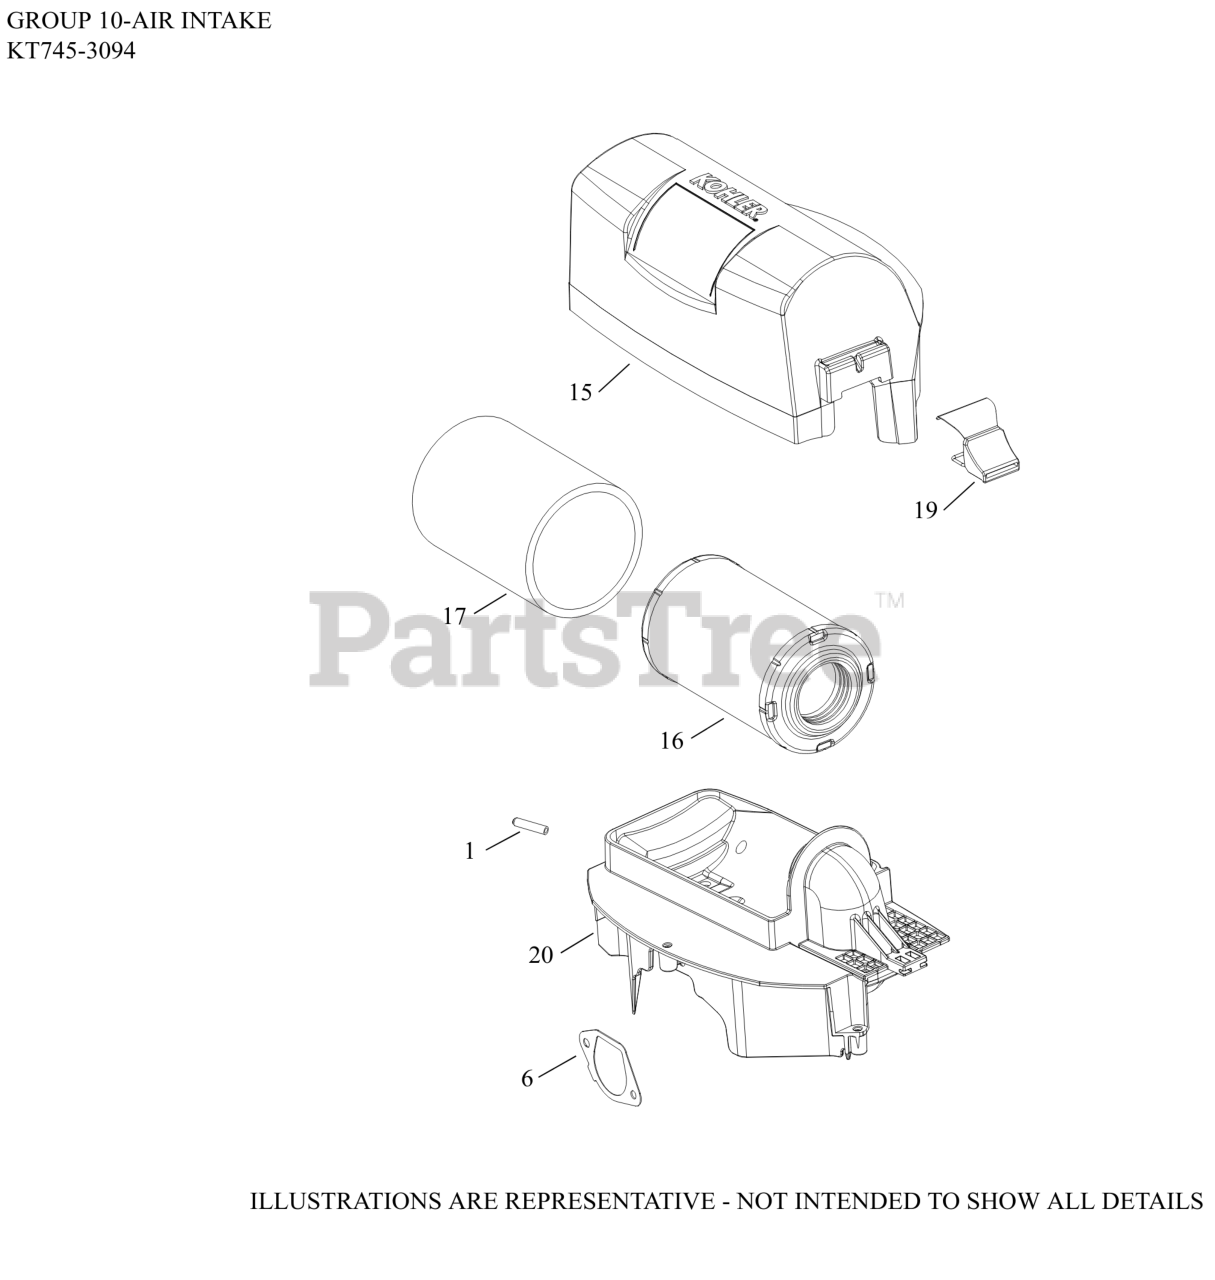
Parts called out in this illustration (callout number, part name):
1	CAP, MASKING
6	GASKET, AIR CLEANER BASE
15	COVER, AIR CLEANER
16	ELEMENT, AIR FILTER
17	ELEMENT, PRE-CLEANER
19	LATCH ASSY, AIR CLEANER COVER
20	BASE ASSEMBLY, AIR CLEANER
